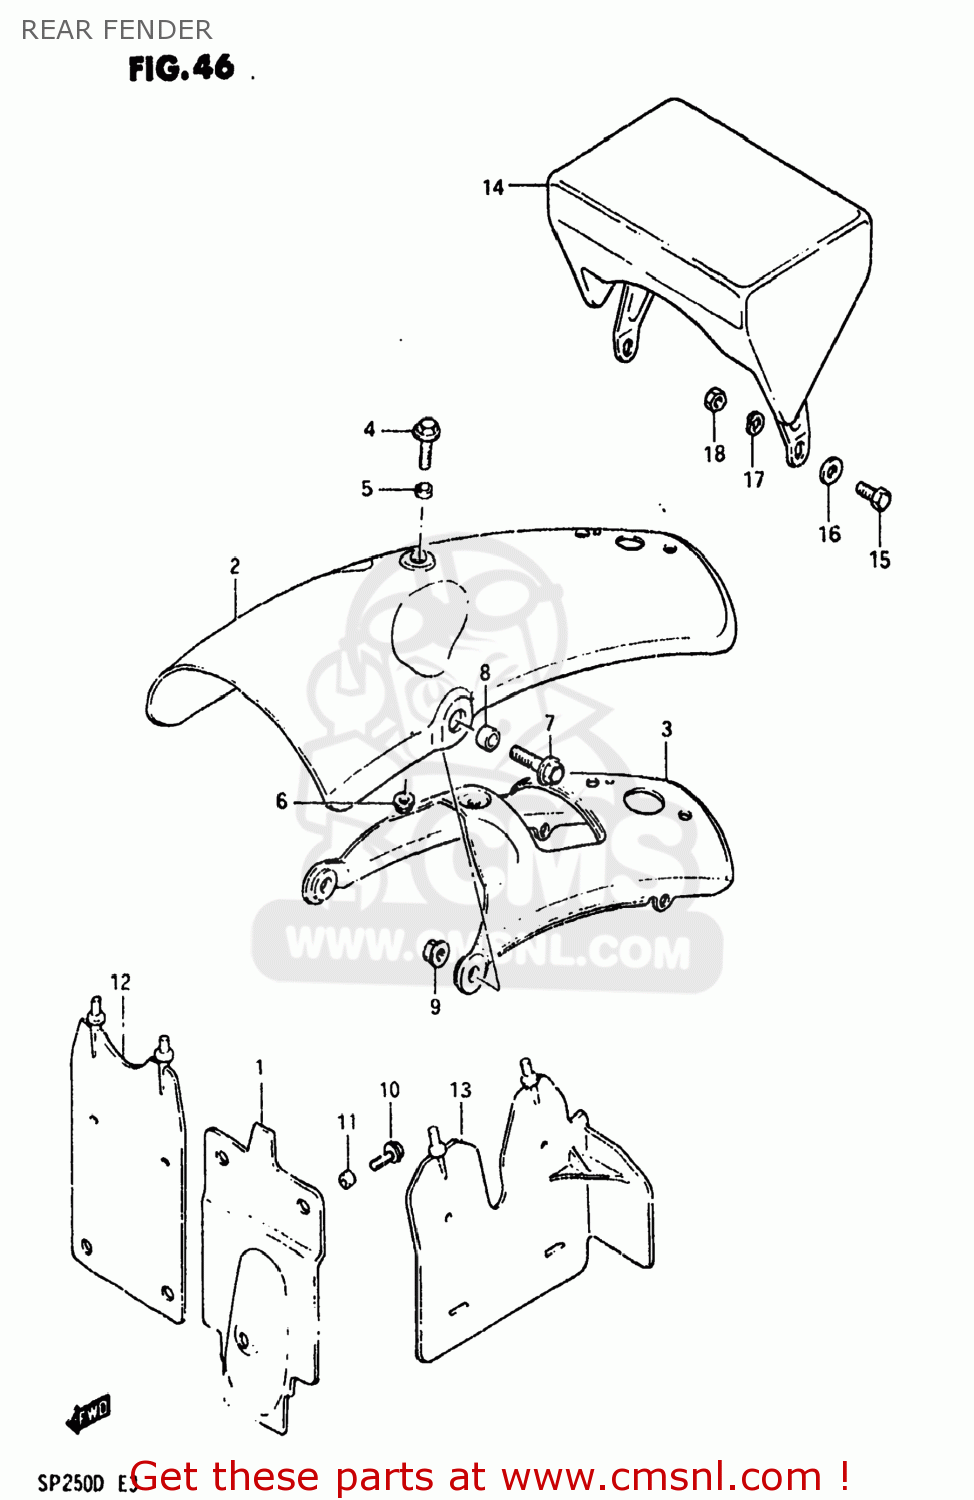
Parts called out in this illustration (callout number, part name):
1	REAR FENDER,FRONT
2	FENDER,REAR
3	REINFORCEMENT
4	BOLT,REAR
5	SPACER
6	NUT
7	BOLT
8	SPACER(8.2X14X4.5)
9	NUT
10	SCREW, FRONT
11	SPACER
12	MUD GUARD,REAR FENDER
13	MUD GUARD
14	BAG ASSEMBLY,SEAT TAIL
15	BOLT
16	WASHER
17	LOCK WASHER
18	NUT
